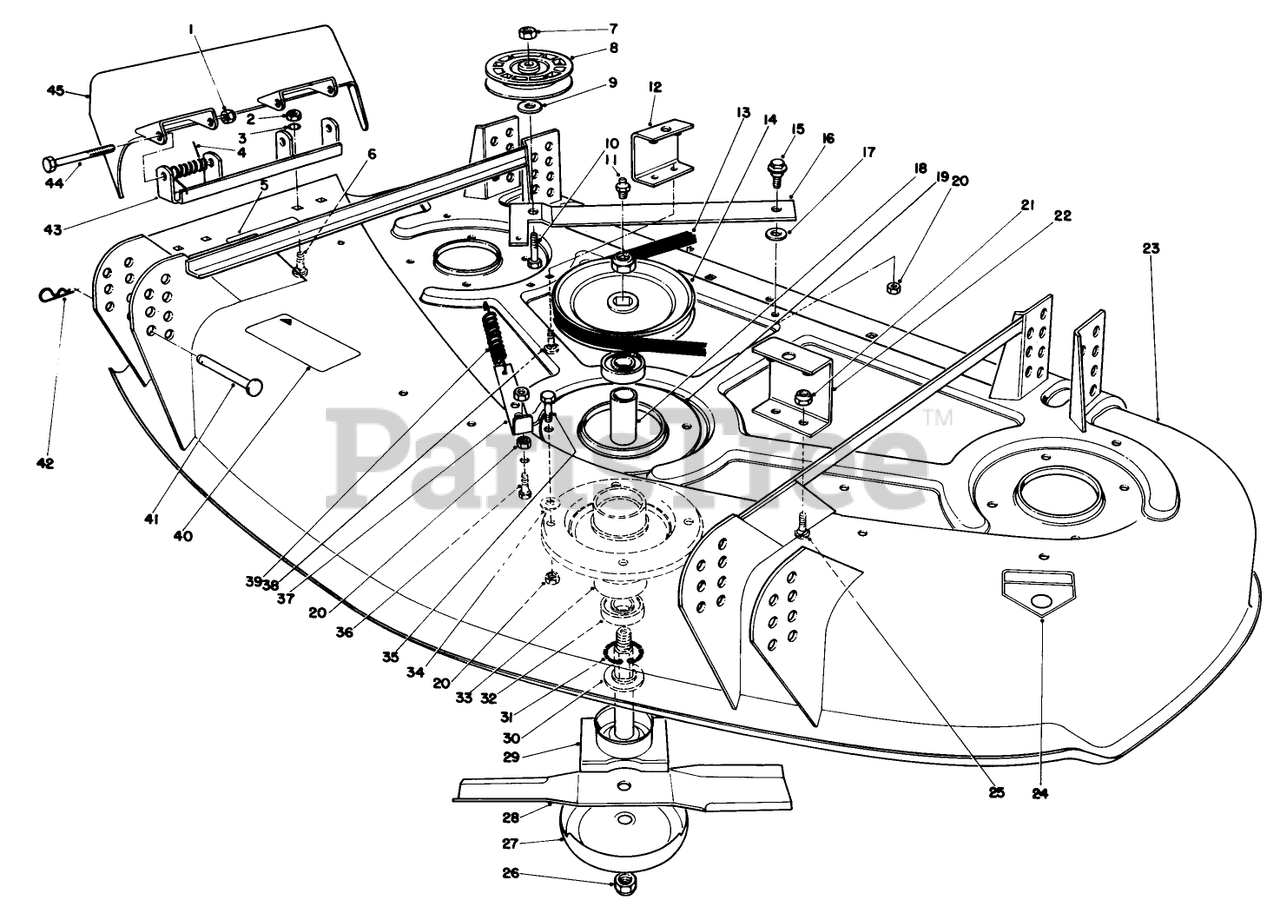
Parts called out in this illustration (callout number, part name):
1	NUT-HEX
2	NUT-HEX
3	WASHER-LOCK
4	SPRING
7	NUT-LOCK, CONE
9	WASHER-FLAT
10	SCREW-HH
11	FITTING-GREASE
13	V-BELT-DECK
15	SCREW-SHOULDER
17	WASHER
20	NUT-LOCK, CONE
21	NUT-LOCK, NI
24	DECAL-DANGER
25	SCREW-CARR
26	NUT-LOCK NI
30	SPACER-SPINDLE
32	BEARING-BALL
34	WASHER-FLAT
35	SCREW-HH
36	SCREW-HH
38	SCREW-CARR
39	SPRING-EXTENSION, DECK
41	PIN-CLEVIS
42	PIN-HAIR
43	PIVOT BRKT WA
44	SCREW-HH
